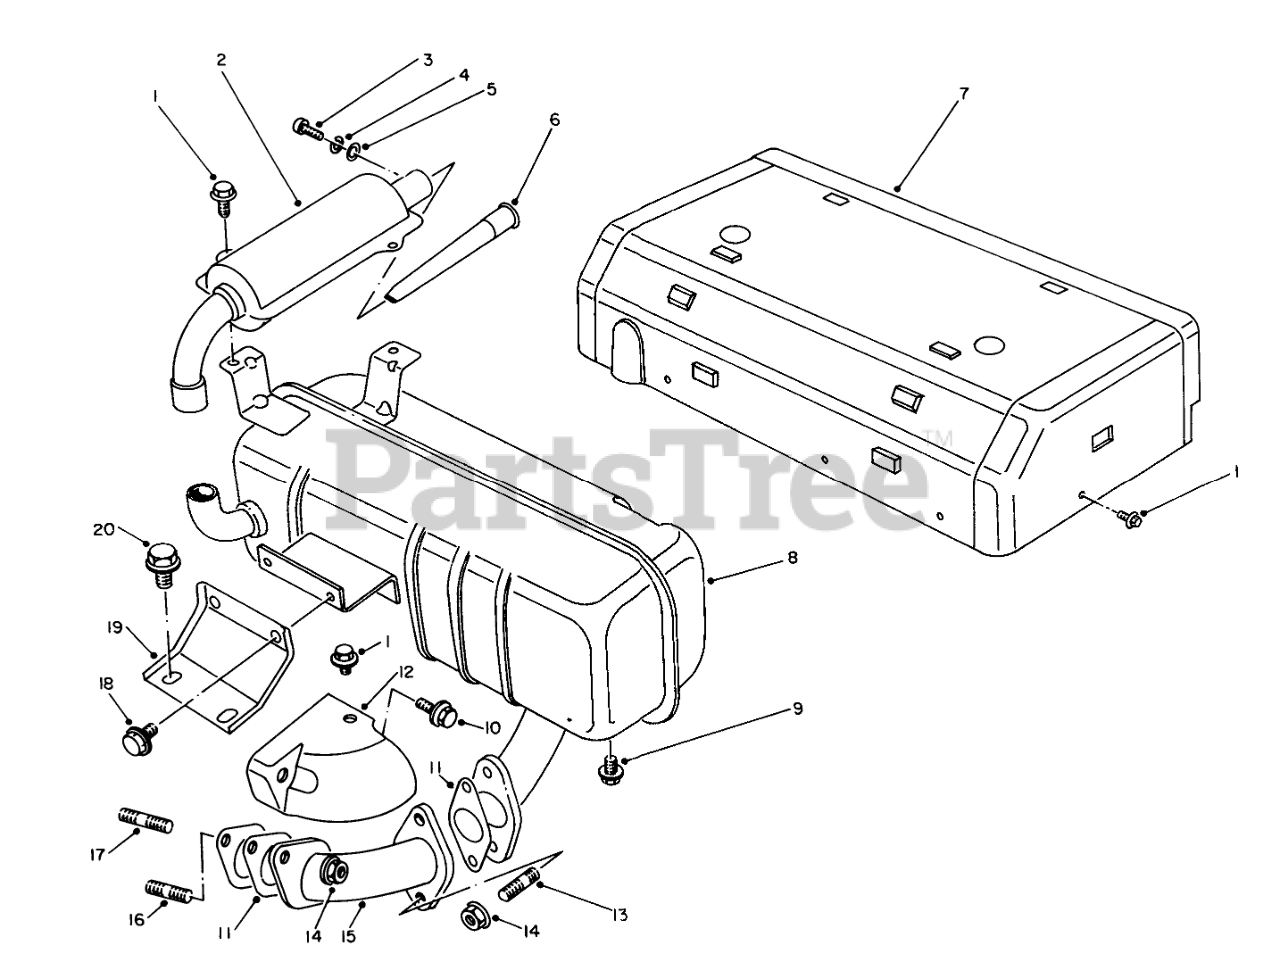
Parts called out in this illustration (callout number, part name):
2	Muffler
4	Lockwasher
5	Washer
6	Screw-Spark Arrester
7	Cover-Muffler
8	Muffler
11	EXHAUST GASKET
12	Cover-Exhaust Pipe
13	Stud Bolt
15	Pipe-Exhaust
16	Stud Bolt
17	Stud Bolt
19	Brace
20	Bolt
